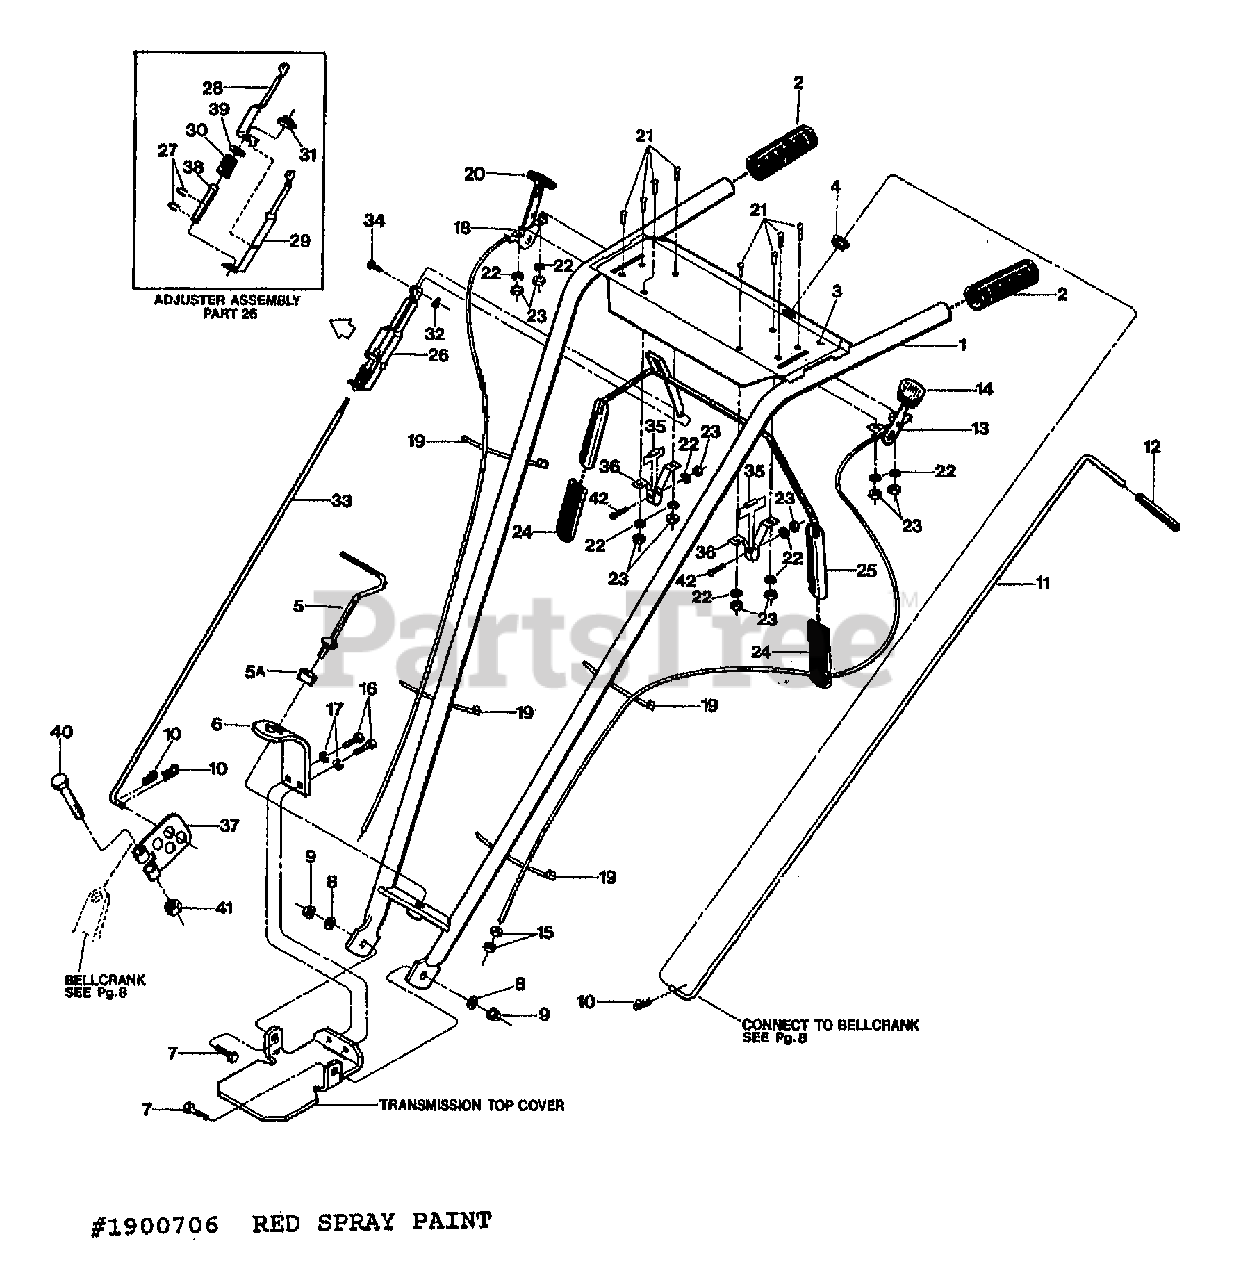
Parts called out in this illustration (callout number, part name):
1	ASSM-HANDLEBAR W/GRIPS (INCL. 2-5A)
2	GRIP-H/B 1" PONY/P-J OPC
3	DECAL-CONTROL PANEL
4	BUSHING-NYLON -PART OF OPERATOR CONTROL PANEL
5	ASSM-STUD H/B
5A	WASHER-1.0X.38X.375
6	PLATE-HANDLEBAR ADJUST
7	SCR-HH 3/8-16X1.0 G5 ZP
8	WASHER-FLAT 3/8 SAE (HANDLEBAR ATTACHMENT)
9	NUT-LOCK 3/8-16 NYLON ZP(HANDLEBAR ATTACHMENT)
10	PIN-CLIP .08
11	ROD-REV W/GRIP OPC (INCL. #9198)
12	GRIP-CONTROL ROD
13	CABLE-WHEEL CLUTCH OPC (INCL. 14,15,19,21-23)
14	KNOB-WHEEL DRIVE CABLE
15	NUT-HEX 5/16-24
16	SCR-HH 3/8-16X.75 G5 ZP
17	WASHER-LK .375 @ DEPL
18	CABLE-THROTTLE PONY OPC
19	TIE-RED (TO SECURE CABLES TO HANDLEBARS)
20	KNOB-THROTTLE CABLE
21	SCR-RH M10-32X.5 MACH
22	WASHER-LK M10
23	NUT-HH M10-32X.125
24	GRIP-PADDLE SM FRAME OPC
25	BAIL W/GRIPS OPC
26	ASSM-ADJUSTMENT OPC (INCL. 27-30, 38-39)
27	RING-KLIP .500 ZINC
28	ADJUSTER-RT SIDE OPC
29	ADJUSTER-LT SIDE OPC
30	SPRING-ADJUSTER OPC
31	WELDNUT 5/16-18
32	RING-KLIP .188 DIA
33	ROD-CONTROL OPC
34	ASSM-PIN & CLIP (SMALL FRAME)
35	SPACER-#10 SPLIT
36	BRACKET-BAIL OPC
38	BUSHING-.5X.334X2.88
39	WASHER-.75X.51X.06 ZP
40	SCR-HH 1/4-20X1.5 G5ZP
41	NUT-LK 1/4-20
42	SCR 10-32
